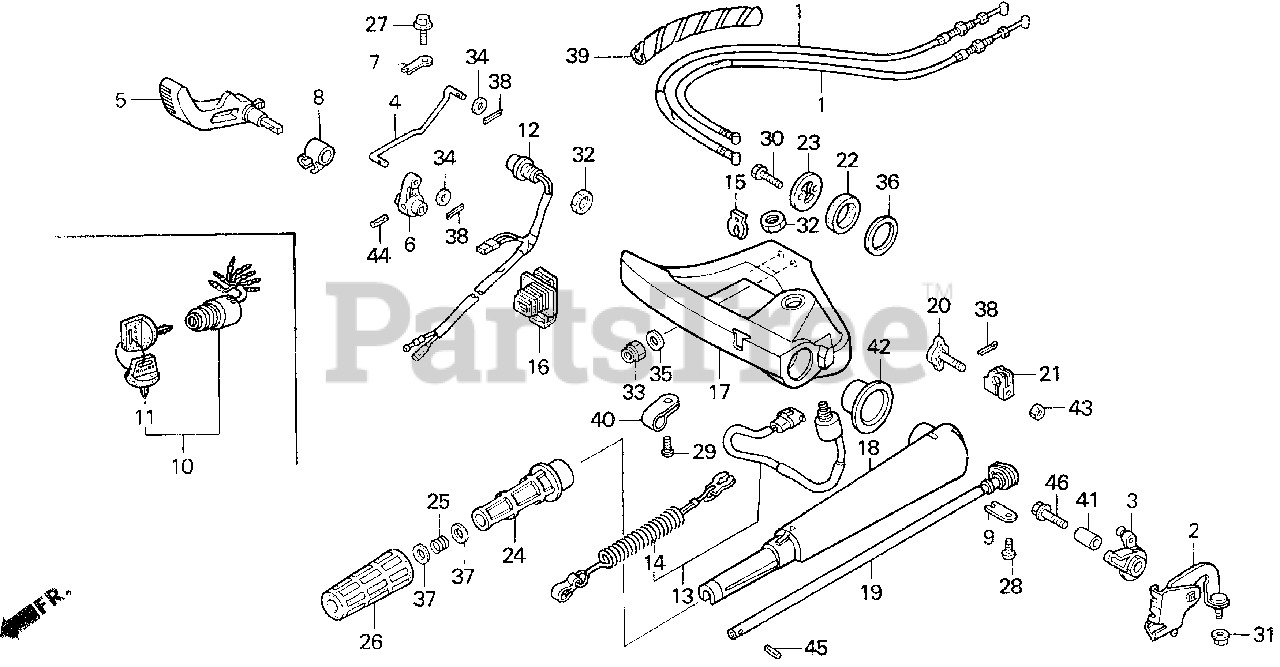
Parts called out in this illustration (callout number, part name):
1	CABLE, THROTTLE
2	BRACKET, THROTTLE CABLE
3	ARM, THROTTLE
5	LEVER, GEARSHIFT
6	LINK A, SHIFT
7	PLATE A, SHIFT LINK
8	COLLAR, DISTANCE
9	PLATE, SHIFT SHAFT
10	SWITCH ASSY., COMBINATION
11	KEY ASSY., COMBINATION SWITCH
13	SWITCH ASSY., EMERGENCY STOP
14	WIRE, EMERGENCY
15	CLIP, EMERGENCY LOCK
16	GROMMET, CASE (LOWER) (A)
17	HANDLE, CARRYING *NH282MU* (OYSTER SILVER METALLIC-U)
18	HANDLEBAR *NH282MU* (OYSTER SILVER METALLIC-U)
19	REEL, THROTTLE
20	BOLT, FRICTION
21	BLOCK, THROTTLE FRICTION
22	RUBBER, HANDLE MOUNTING
23	PLATE, HANDLEBAR
24	PIPE, GRIP
25	SPRING, GRIP PIPE
26	RUBBER, GRIP
27	BOLT, FLANGE (6X12)
28	SCREW, PAN (6X8)
29	SCREW, PAN (5X12)
30	BOLT, HEX. (6X16)
31	NUT, SELF-LOCK (6MM)
32	NUT, HEX. (16MM)
33	NUT, SELF-LOCK (10MM)
34	WASHER, PLAIN (5MM)
35	WASHER (10MM)
36	WASHER, HANDLEBAR (36MM)
37	WASHER (10MM)
38	PIN, SPLIT (2.0)
39	TUBE, SPIRAL
40	CLIP, WIRE HARNESS
41	COLLAR, DISTANCE (6.5X10.5X16)
42	COLLAR, HANDLEBAR
43	NUT, HEX. (6MM)
44	PIN, SPRING (4X20)
45	PIN, SPRING (4X28)
46	BOLT, FLANGE (6X28)
